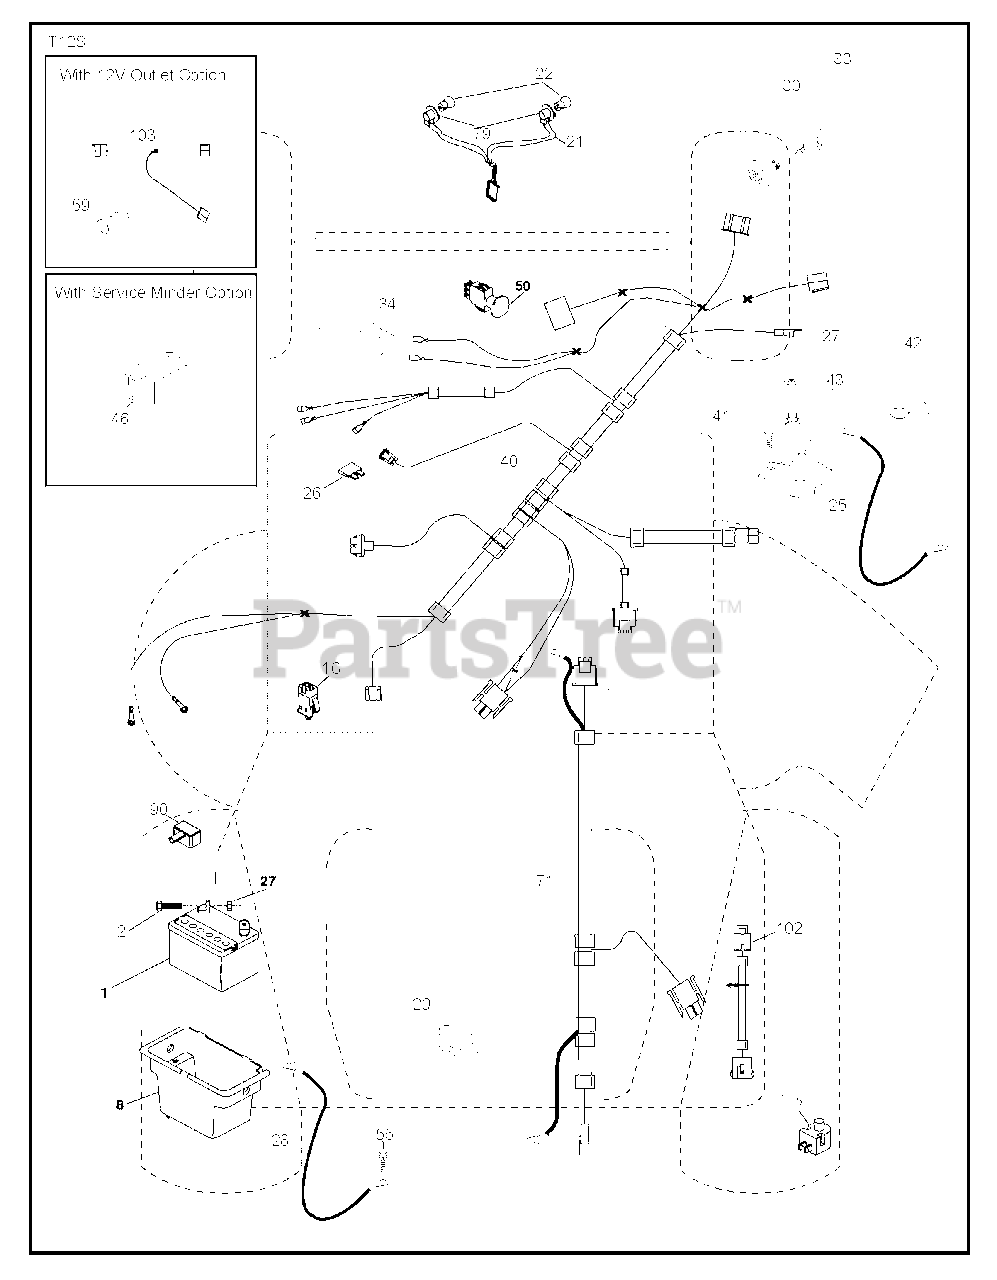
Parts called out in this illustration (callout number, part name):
1	Battery, Dry 30 Amp
2	BOLT.HEX.1/4.X.3/4.DICHROMATE
8	BOX.BATTERY.MNT.REAR.L
16	SWITCH INTERLOOK PUSH-IN
21	HARNESS.LIGHT W/4152J BULBS
25	CABLE.STARTER.6GA.BL/RED.14.
26	FUSE 20AMP
27	NUT
28	CABLE.BLACK.18"REAR.BA
29	SWITCH.SEAT.DELTA.OPC.
30	SWITCH.IGN.DELTA.W.LGH.ROS
33	KEY.CHAIN.BLISTER.PACK.GEN.INT
40	HARNESS.IGN.DASH.HUQ/P
41	SCREW
42	TERMINAL COVER
43	SOLENOID.W/BRASS.PLUNGER
46	RP GUAGE.SRVCMNDR.HRMTR.
50	RB PTO.SWITCH.8 TERMINAL.BLACK
55	SCREW 5/16"
71	HARNESS.IGN.CHASS.TEX.REAR.BAT
79	BULB HOLDER ASM.
90	COVER.TERMINAL.BATTERY
102	HARNESS PIGTAIL PCH TEX ROS
105	REVERSE SWITCH
